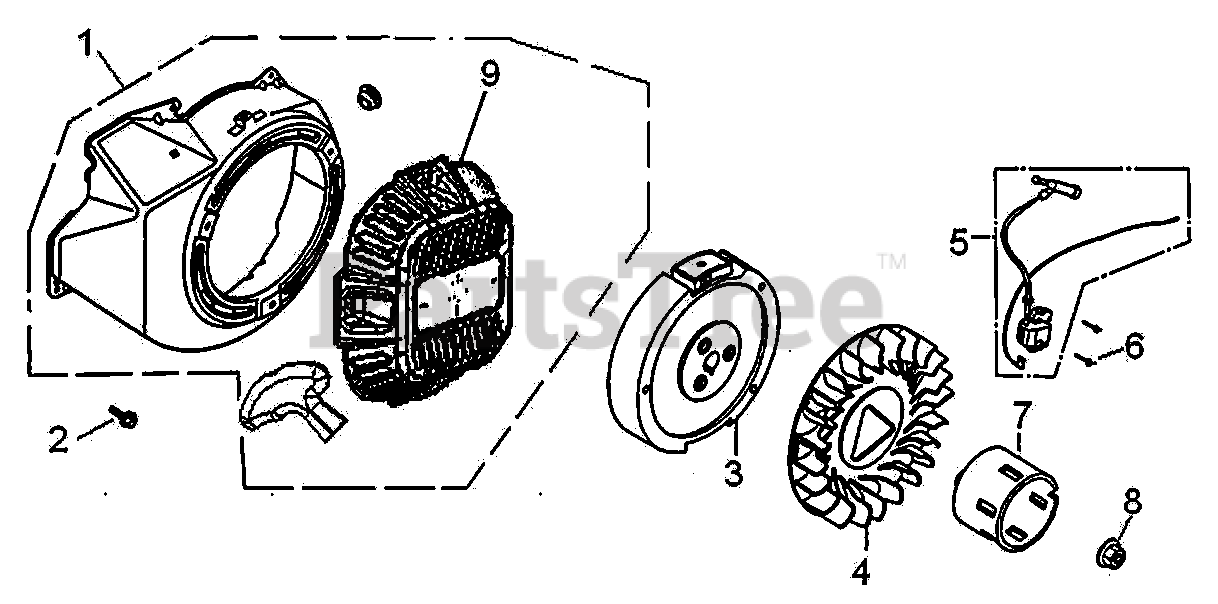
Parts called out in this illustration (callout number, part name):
1	STARTER ASSY.
2	BOLT, FLANGE
3	FLYWHEEL COMP
4	FAN, COOLING
5	COIL ASSY ., IGNITION
6	BOLT, FLANGE, 6X25
7	PULLEY, STARTER
8	NUT, SPECIAL
9	RECOIL COVER ASSY
